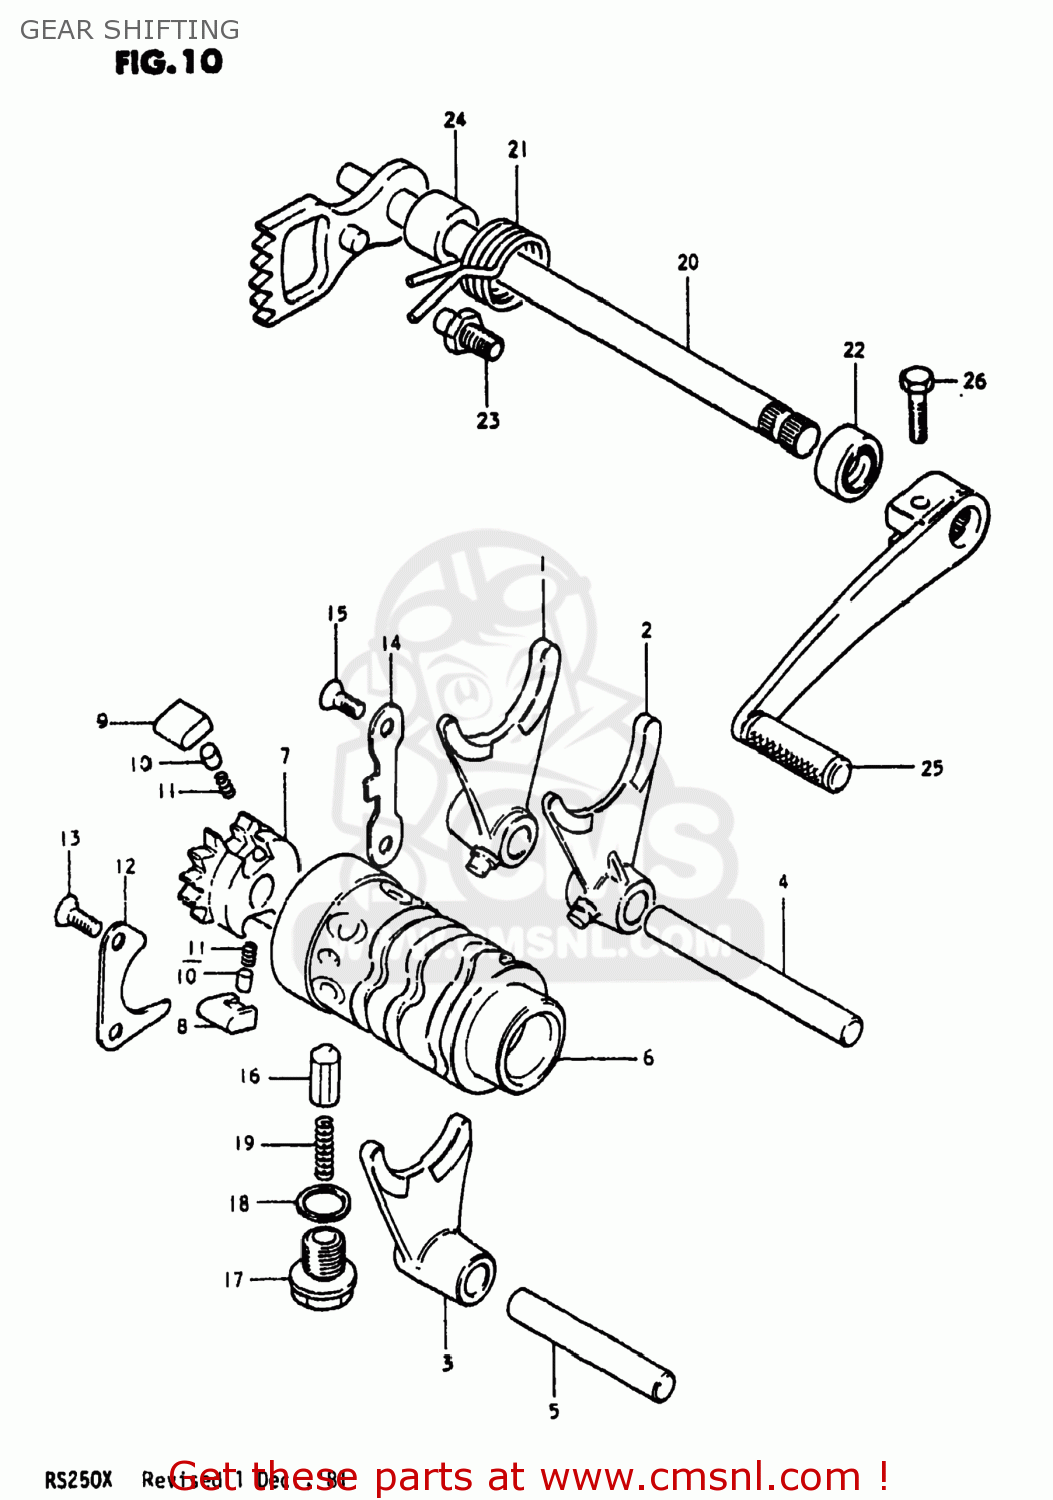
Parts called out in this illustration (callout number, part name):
1	FORK,GEAR SHIFT NO.1
2	FORK,GEAR SHIFT NO.2
3	FORK,GEAR SHIFT NO.3
4	SHAFT,GEAR SHIFT FORK
5	SHAFT,GEAR SHIFT FORK
6	CAM,GEAR SHIFT
7	RETAINER,GEAR SHIFT CAM
8	PAWL,GEAR SHIFT NO.1
9	PAWL,GEAR SHIFT NO.2
10	PIN(5X8)
11	SPRING
12	LIFTER,GEAR SHIFT PAWL
13	SCREW
14	GUIDE,GEAR SHIFT CAM
15	SCREW
16	STOPPER,GEAR SHIFTING
17	BOLT,GEAR SHAFT CAM STOPPER
18	GASKET(14X19.2X2) (NAS)
19	SPRING
20	SHAFT,GEAR SHIFT
21	SPRING
22	OIL SEAL
23	STOPPER,GEAR SHIFT CAM
24	SPACER(12X20X15.3)
25	LEVER ASSEMBLY,GEAR SHIFTING
26	BOLT
